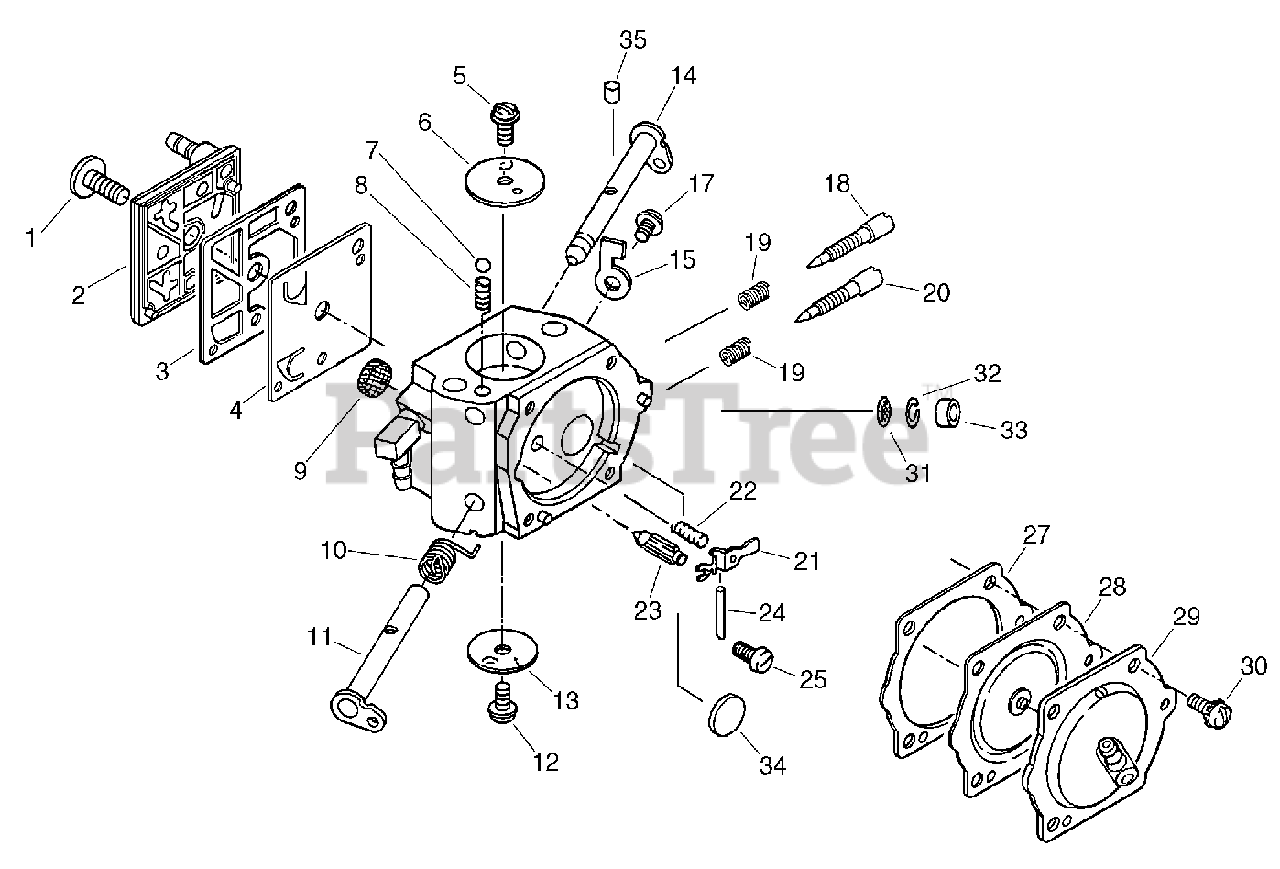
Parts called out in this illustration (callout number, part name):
2	COVER, FUEL PUMP
3	GASKET, FUEL PUMP
4	DIAPHRAGM, FUEL PUMP
6	VALVE, CHOKE
7	BALL, CHOKE FRICTION
9	SCREEN, FUEL INLET
10	SPRING, THROTTLE RETURN
11	SHAFT, THROTTLE
13	VALVE, THROTTLE
14	SHAFT, CHOKE
15	STOP, THROTTLE
18	NEEDLE, HIGH SPEED
19	SPRING, NEEDLE
20	NEEDLE, LOW SPEED
21	LEVER, METERING
23	VALVE, INLET NEEDLE
24	PIN, METERING LEVER
25	SCREW, METERING LEVER PIN
27	GASKET, METERING DIAPHRAGM
28	DIAPHRAGM, METERING
29	COVER, METERING DIAPHRAGM
31	SCREEN, SPARK ARRESTER
32	RING, RETAINING
33	PLUG, CUP
34	PLUG, WELCH
35	PLUG, FRICTION
